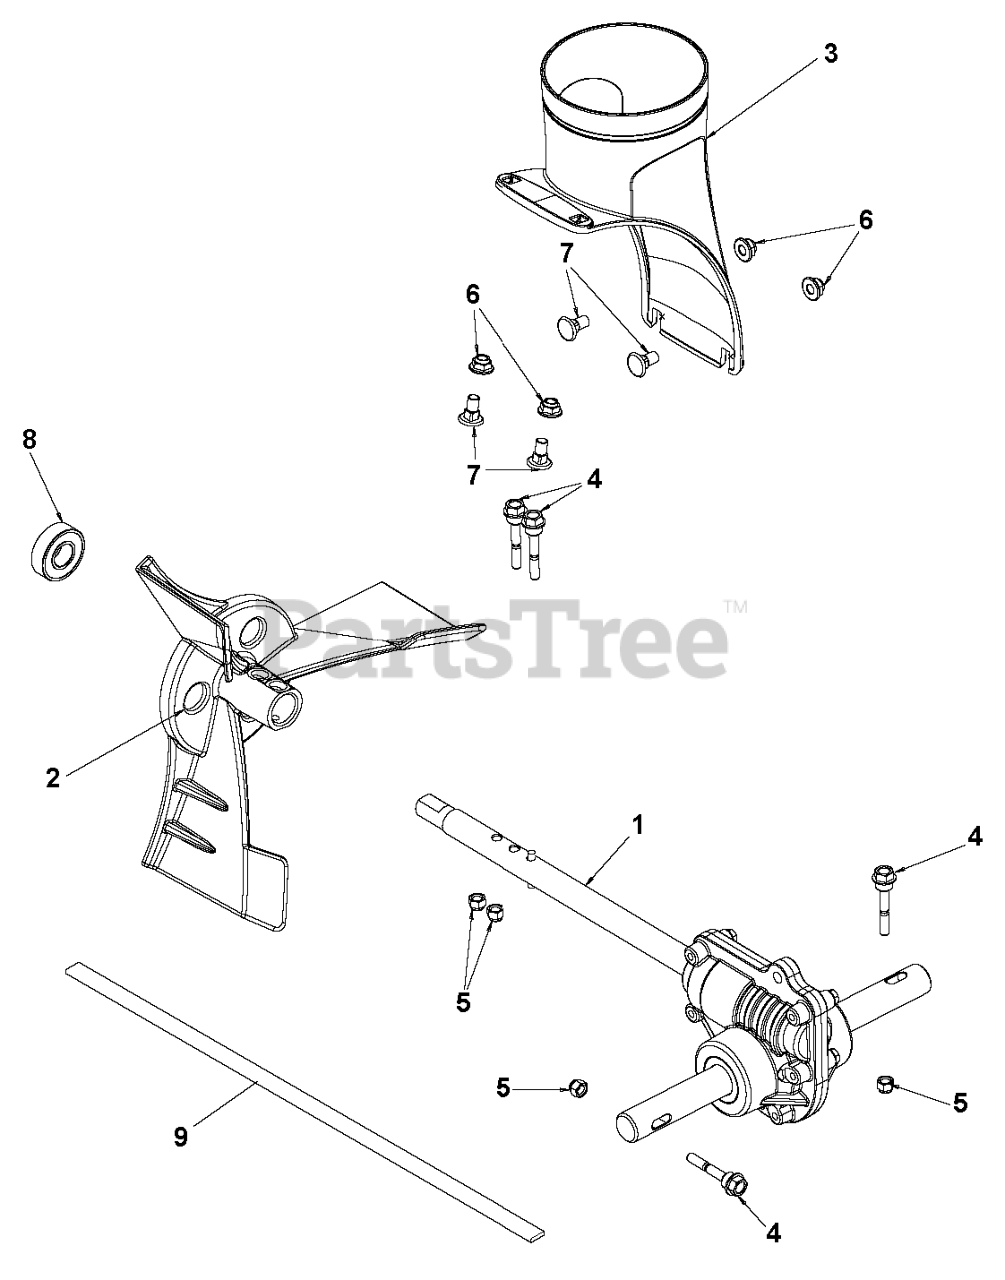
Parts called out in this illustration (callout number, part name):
1	GEARBOX CAST DD SHAFT
3	CHUTE BASE CAST ALUM HUSQ SIL
4	BOLT SHEAR HX HD 1/4-20 CLEAR
5	NUT HEXAGON 1/4-20 ST ZPB
6	NUT HEX FLG NYLOCK BLK 5_16-1
7	BOLT CARR WAFER BLK 5_16-18 X
